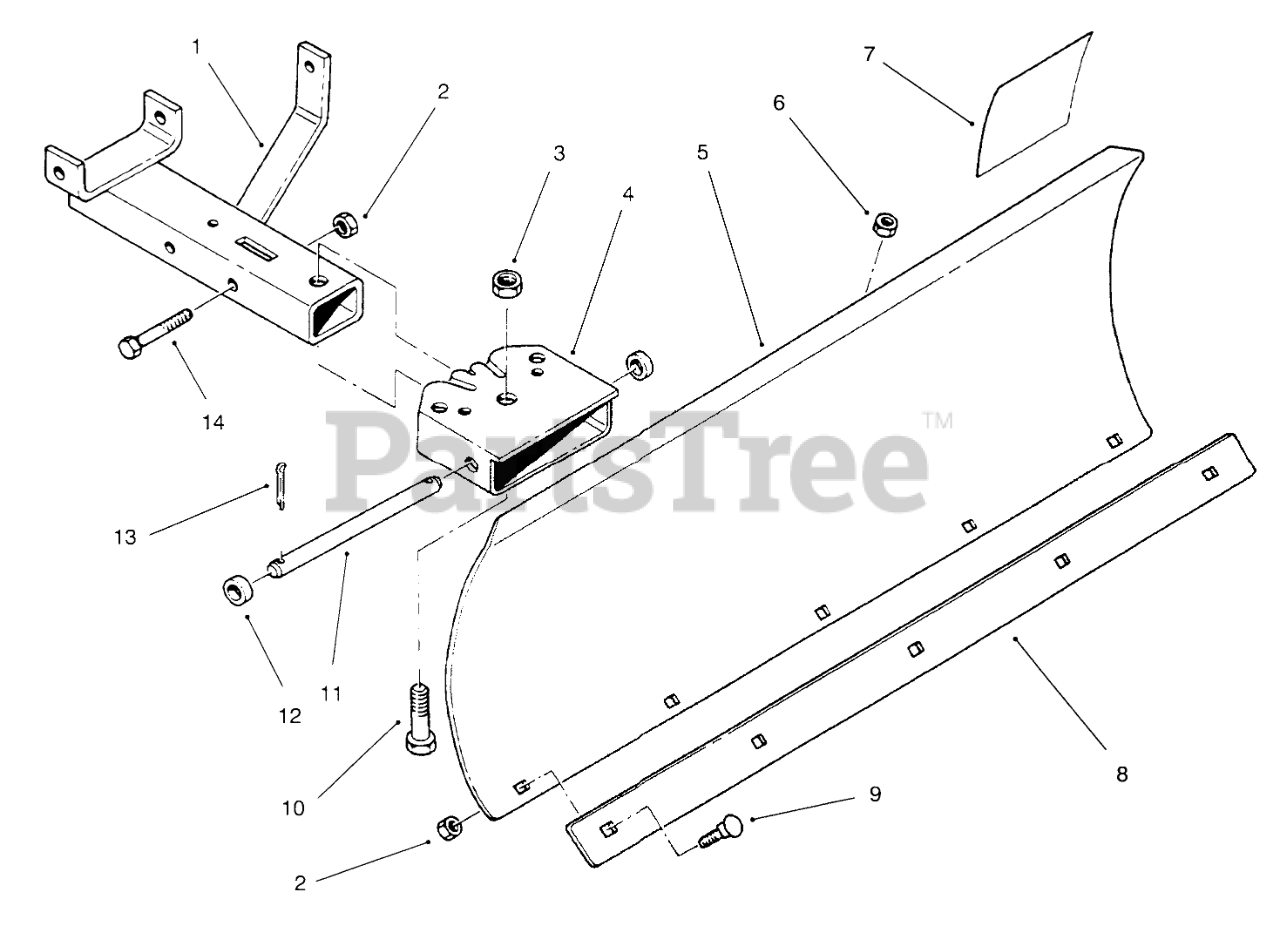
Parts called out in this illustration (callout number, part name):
1	Frame
2	NUT-LOCK, NI
3	NUT-LOCK, NI
4	Quadrant
5	Blade
6	NUT-JAM
7	DECAL - DANGER
8	Plate
9	SCREW-CARR
10	SCREW-HH
11	ROD-LOWER
12	SPACER
13	PIN-COTTER
14	SCREW-HH
